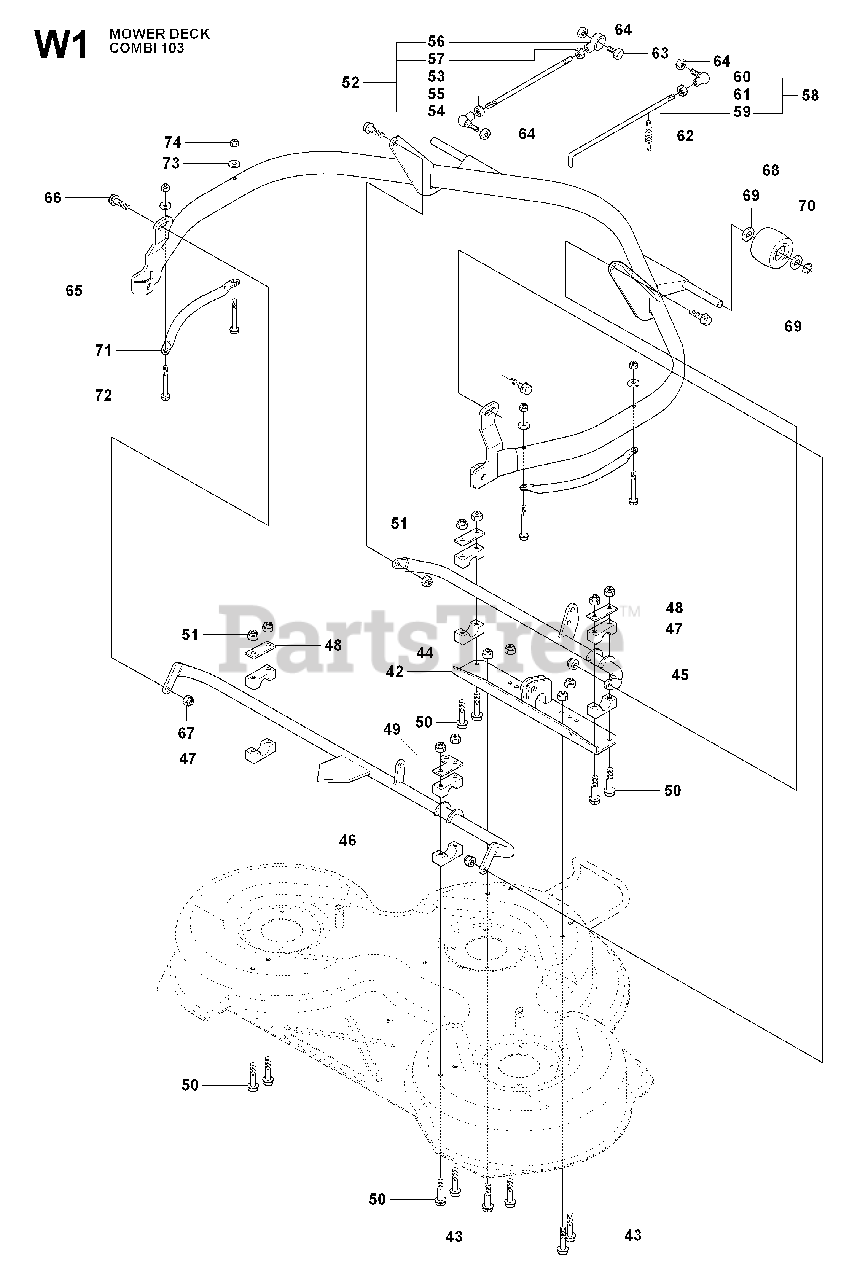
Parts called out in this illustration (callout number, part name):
44	LOCKNUT M8
51	LOCKNUT M8
52	PARALLEL RODY ASSY
58	CLUTCH ROD ASSY
67	LOCKNUT M8
68	DECK ROLLER, FRONT
70	RETAINING RING SGA 15
73	WASHER
74	LOCKNUT M6
